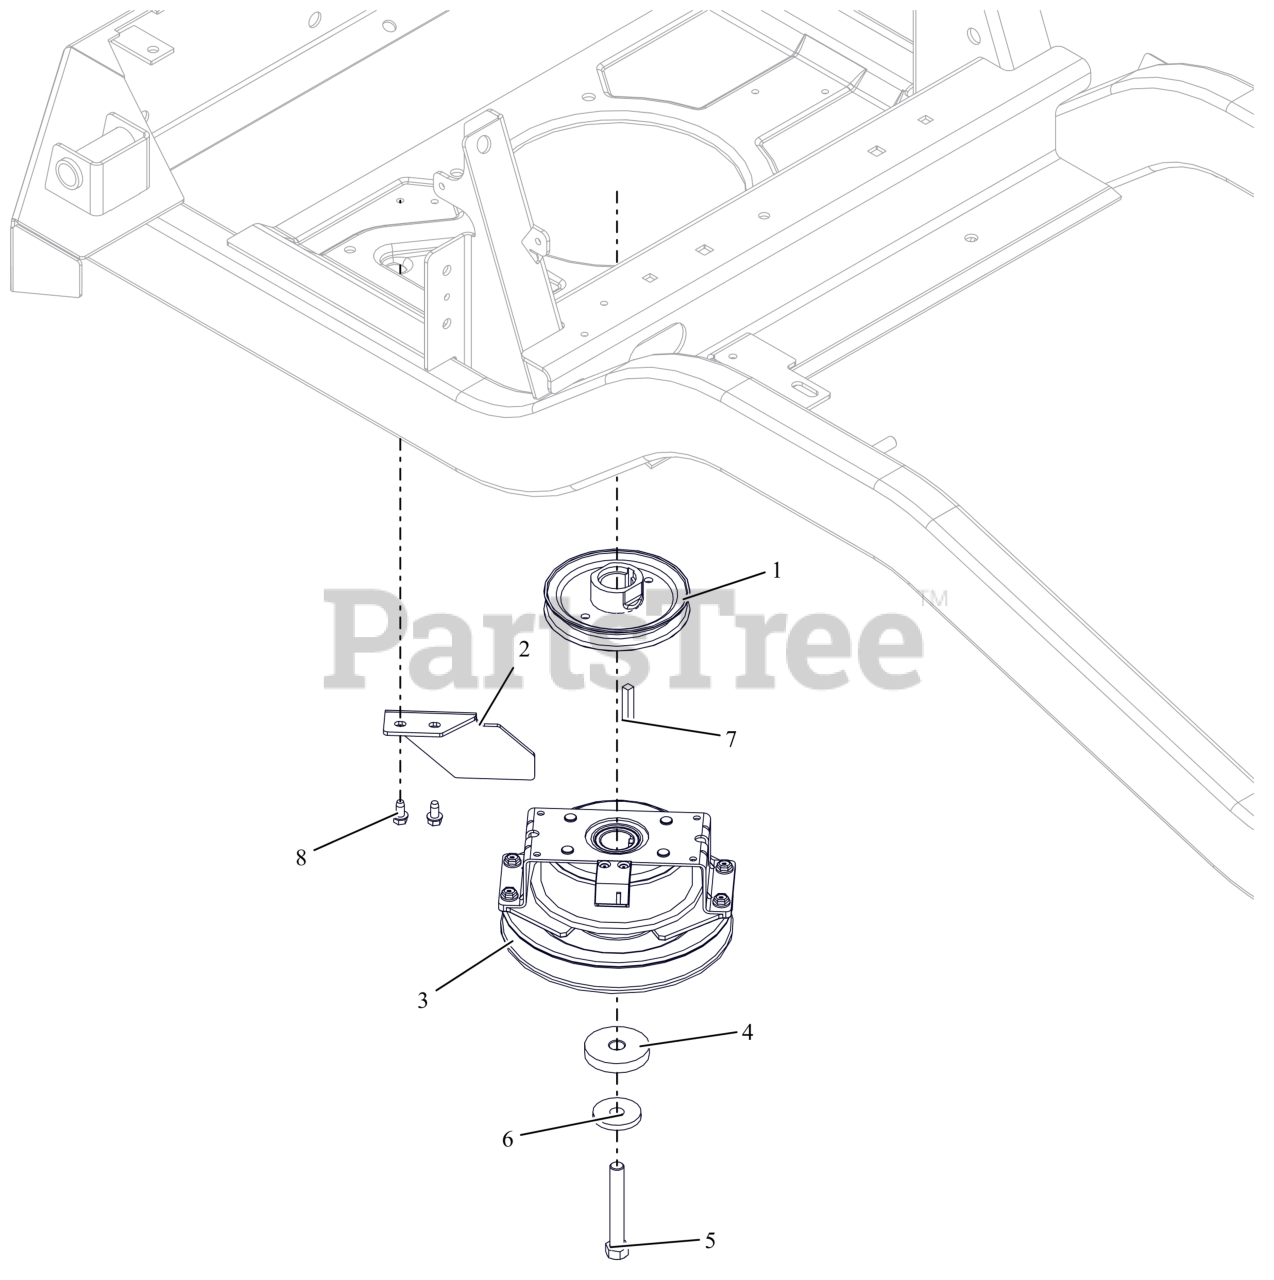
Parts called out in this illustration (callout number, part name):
1	WLDMT,PULLEY-4.50ODX1.003
2	BRKT, CLUTCH STOP HD
3	CLUTCH, OGURA DBL SPRG
4	SPACER, .474/.459X2.00X.350
5	BLT, HEX .44-20X3.00 G8 ZCC NT
6	WASHER, 7/16" SPRING DISK
7	KEY-SQ .25 X 1.25 X .25 SAE
8	SCR-TAP .25-20X.50 HWH ZCC
